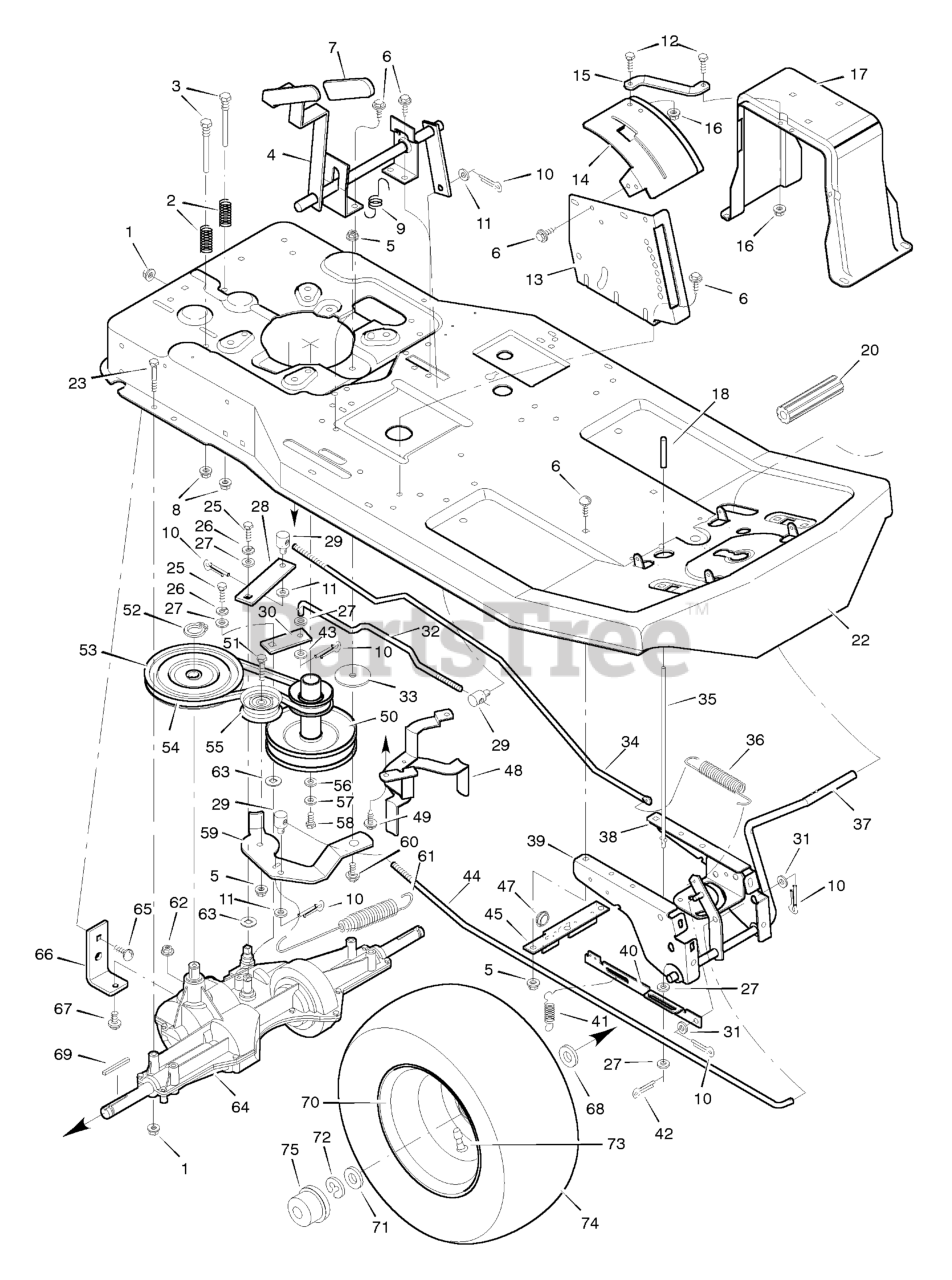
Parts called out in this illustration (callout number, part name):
1	Locknut, Flange
2	Spring, Compression
3	Guide, Belt
4	Shifter Assembly
5	Locknut, Flange
7	Grip, Shift Lever
8	Hex Nut
9	Spring, Extension
10	Pin, Cotter
11	Washer
12	Bolt, Hex
13	Plate, Index
14	Gate, Shift
15	Brace, Shift Gate
16	Locknut, Flange
17	Support, Seat
18	Grip, Parking Brake
20	Pedal, Rubber
22	Frame Assembly
23	Bolt, Hex
25	Bolt, Hex
26	Lockwasher
28	Yoke, Brake
29	Nut, Adjusting
30	Yoke, Shift
31	Washer
32	Rod, Shift
33	Washer, Hardened
34	Rod, Brake
35	Rod, Parking Brake
36	Spring, Extension
37	Lever, Pedal
38	Plate, Left Suspension
39	Plate, Right Suspension
40	Link, Parking Brake
41	Spring, Extension
42	Pin, Cotter
44	Rod, Clutch
45	Stop, Parking Brake
47	Grommet
48	Guide, Belt
50	Pulley Assembly, Stack
51	Bolt, Hex
52	Ring, Retainer
53	Pulley, Drive
54	Belt, Motion Drive
55	Pulley, Idler
57	Lockwasher
58	Bolt, Hex
59	Bracket, Idler
60	Bolt, Shoulder
61	Spring, Extension
62	Locknut, Hex
64	Transaxle, Dana Model 4450-1 **
65	Bolt, Carriage
66	Bracket, Transaxle
67	Bolt, Hex
69	Key, Square
70	Wheel & Tire Assembly
72	E-Ring Stem
73	Valve
74	Tire *
75	Hub Cap
